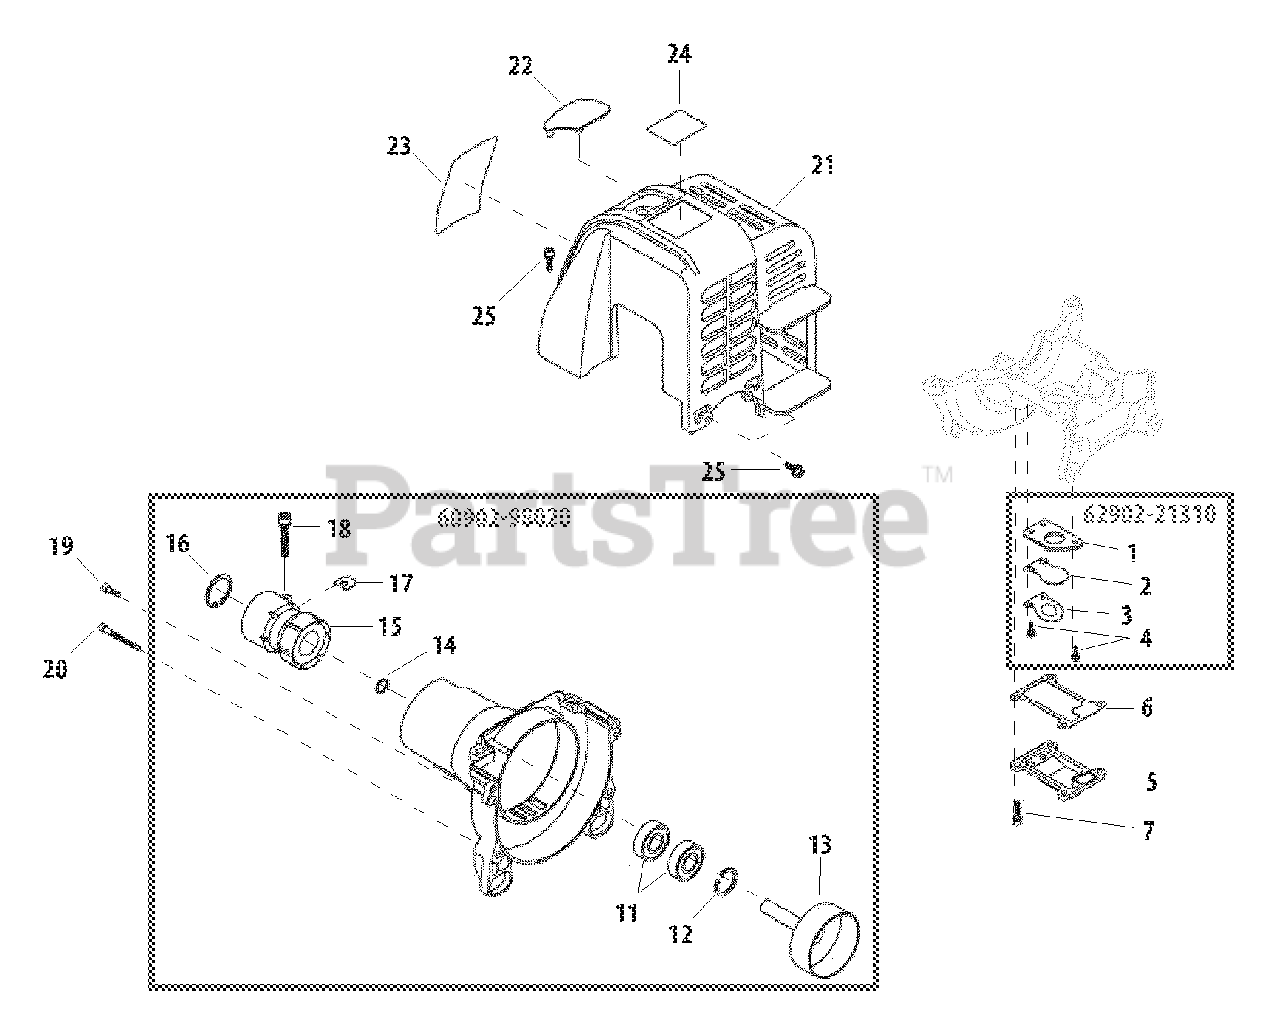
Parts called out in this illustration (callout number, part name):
1	PLATE, REED BACKING
2	VALVE, REED
3	STOP, REED VALVE
4	SCREW - 3X10
5	COVER, REED VALVE
6	GASKET, REED VALVE
7	SCREW - 4X12
11	BEARING, BALL - 6000
12	RING, RETAINING - 26
13	DRUM, CLUTCH
14	RING, RETAINING
15	CLAMP, MAIN PIPE
16	RING, RETAINING - 40
17	SHIM
18	SCREW - 5X22
19	SCREW - 5X16
20	SCREW - 5X35
21	COVER, ENGINE
22	GROMMET
23	LABEL - C4
24	LABEL - TRADE
25	SCREW - 4X16
60902-98020	FAN CASE ASSY
62902-21310	REED VALVE ASSY
